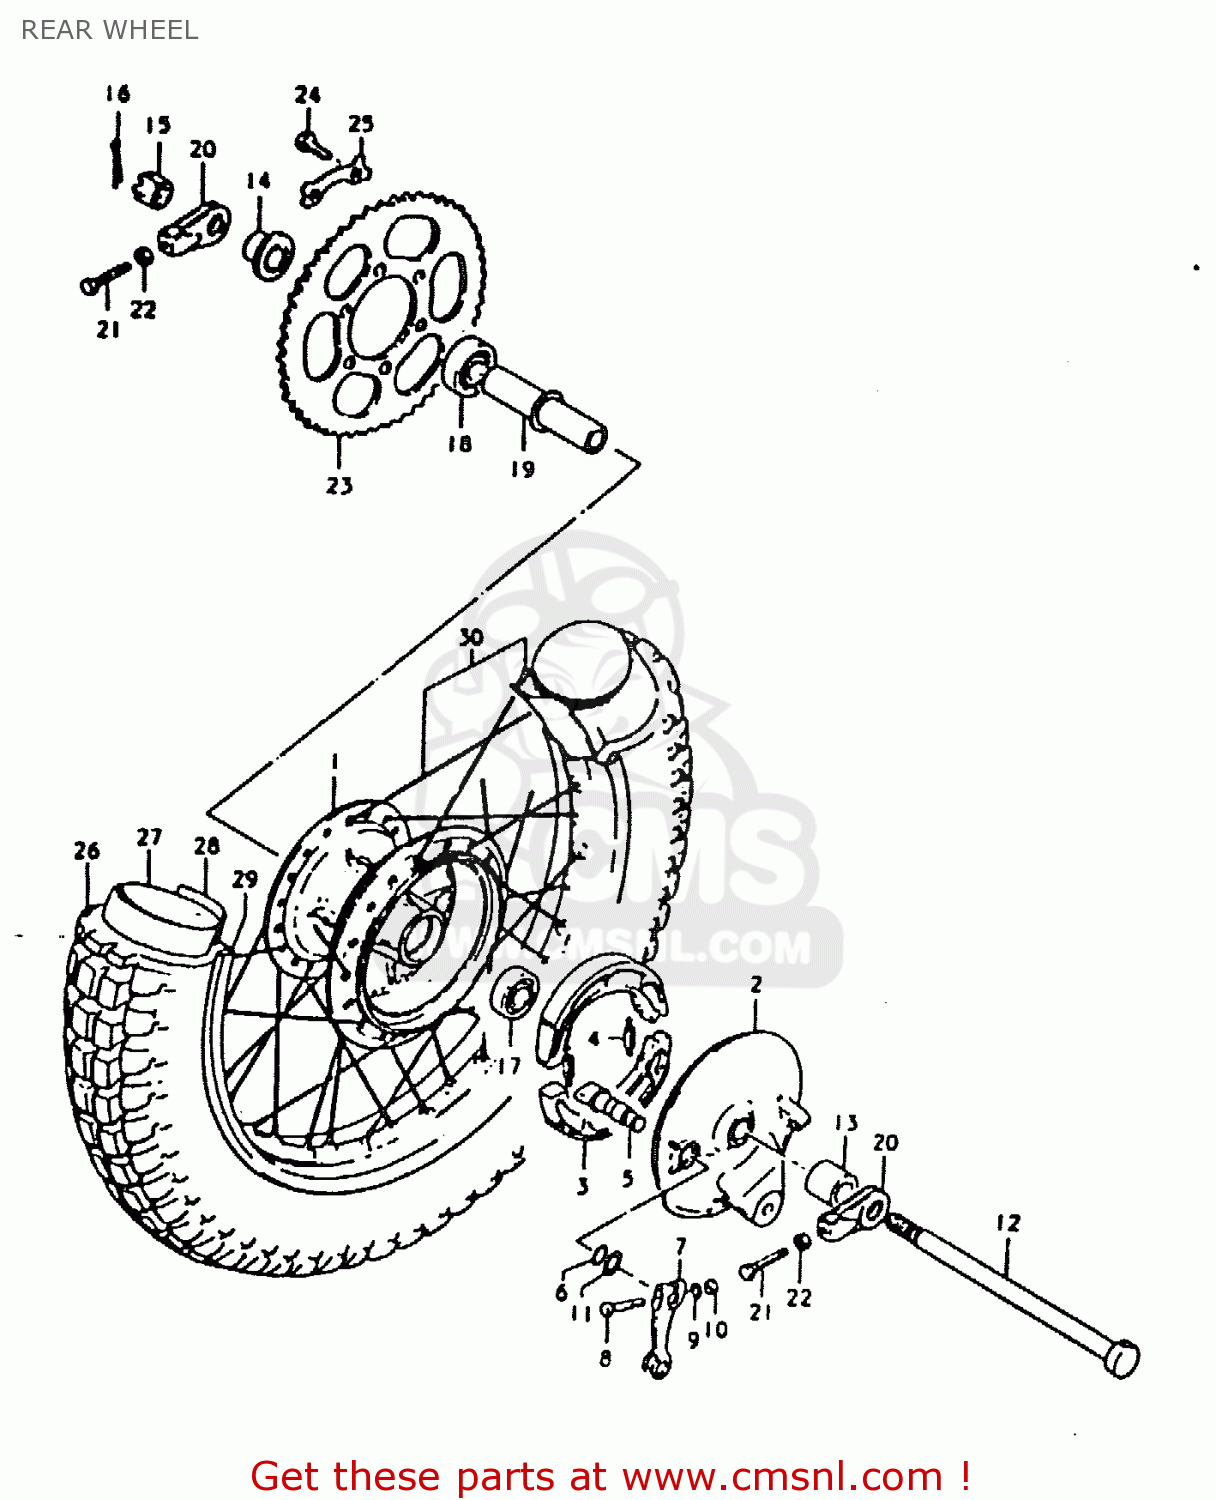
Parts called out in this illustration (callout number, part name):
1	HUB,REAR WHEEL
2	PANEL,RR BRAKE ANCHOR
3	SHOE,BRAKE
4	SPRING(L:34)
5	CAM,FRONT BRAKE
6	O-RING (D:2.4 ID:13.8)
7	LEVER,RR BRAKE CAM
8	BOLT(6X33)
9	WASHER
10	NUT
11	WASHER (14.5X22X1.6)
12	AXLE,REAR
13	SPACER(15.2X22X26)
14	SPACER,RR AXLE,L
15	NUT
16	COTTER PIN
17	BEARING
18	BEARING
19	SPACER,RR WHEEL HUB BEARING
20	ADJUSTER,CHAIN
21	BOLT(8X40)
22	NUT
23	SPROCKET,REAR
24	BOLT(8X30)
25	WASHER
26	TIRE 4.10-18 105-458MM
27	TUBE ASSEMBLY,WHEEL,INNER
28	PROTECTOR,INNER TUBE
29	RIM,WHEEL(1.85X18)
30	SPOKE SET,REAR
